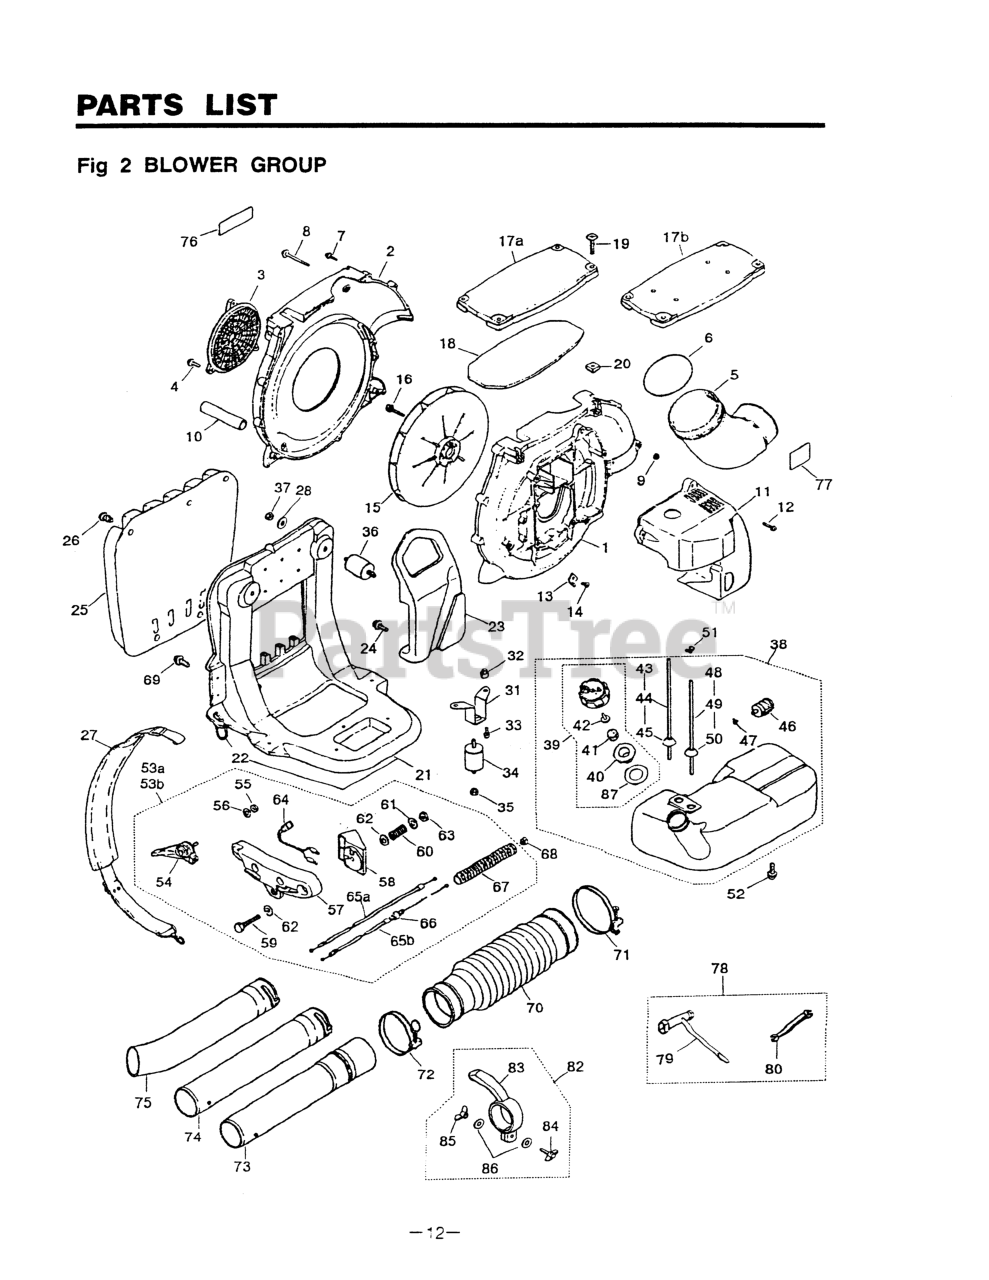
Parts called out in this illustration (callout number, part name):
1	CASE, VOLUTE
2	COVER, VOLUTE
3	NET, GUARD (RPLS-12222)
6	O-RING
7	SCREW
9	NUT (B)
11	COVER, ENGINE (RPLS-11210)
12	SCREW
15	FAN (REPLACES 3490-12110)
16	BOLT (RPLS 3405-12211)
17B	COVER (RPLS -13110)
18	COVER, PACKING
19	SCREW
20	NUT
22	RING (USE -21121)
23	HANGER (RPLS -21210)
25	PAD (RPLS -21310)
26	CLIP (RPLS 3490-21320)
28	WASHER, FLAT
31	BRACKET (RPLS -22510)
32	WASHER
33	SCREW, M5X20 (RPLS.1400-75510)
34	MOUNT (A) (RPLS 3490-22110)
35	NUT, M6 X 5
36	MOUNT (B) (RPLS 3405-22120)
37	NUT, M6 X 5
38	TANK ASSY (RPLS -23005)
39	CAP ASSY (RPLS -23202)
40	INNER CAP
43	PIPE (RPLS 3490-23410)
44	PIPE (USE 1696-85400)
45	GROMMET
46	FILTER ASSY
47	CLIP (REPLACES 2841-31280)
48	PIPE ASSEMBLY
49	PIPE (USE 1620-81710)
50	GROMMET
51	CLIP
52	SCREW, M5 x 12
53B	LEVER (EB441)
54	LEVER, THROTTLE
55	NUT (B)
56	WASHER, M5x.8(RPLS 01624-20508
58	BRACKET
59	BOLT
60	SPRING
61	WASHER
62	WASHER, FLAT
63	NUT, M6 X 5
64	SWITCH, STOP
65B	CABLE COMP,THROTTLE EB441
66	NUT, M6 X 5
67	TUBE (USE 5548-73310)
68	NUT, M6 X 5
69	BOLT
70	HOSE, FLEXIBLE
71	2756-51510 (RPLS. 07280-09832)
73	JOINT, SWIVEL
74	PIPE, EXTENSION
75	PIPE, BENT
78	TOOL SET
80	SPANNER, 8 X 10 (RPLS 2540- )
82	BLOWER ASSIST HANDLE
83	EBH100
84	BOLT, WING
85	NUT, WING
86	WASHER
87	PACKING (RPLS -85321)
